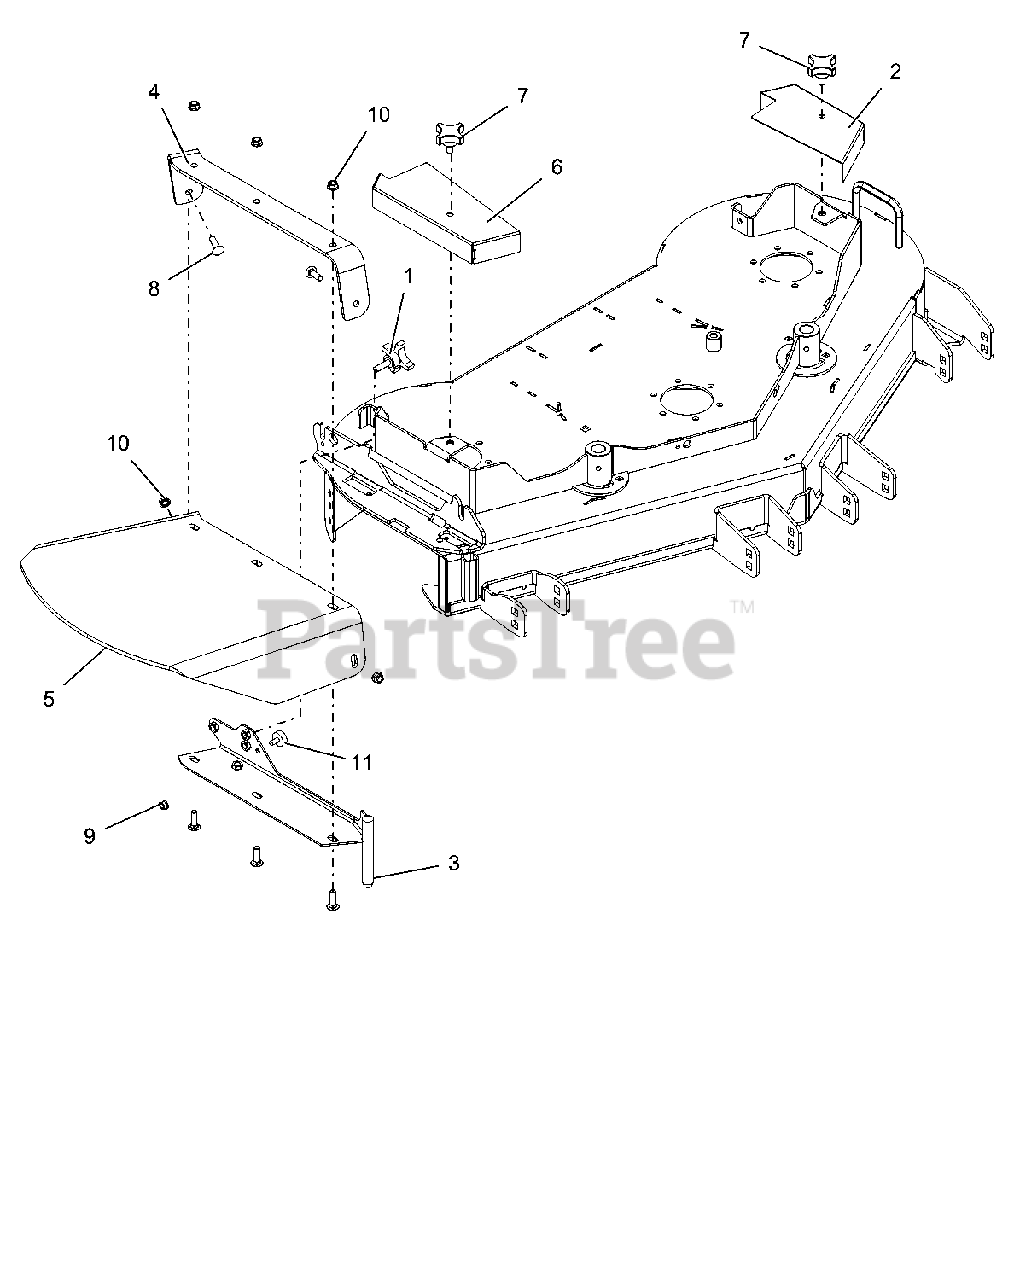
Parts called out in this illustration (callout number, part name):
1	KNOB, 3/8 X 1.25 - 4 PRONG
2	SHIELD, LH SPINDLE 48 FLWLK-RED
3	WLDT. DISCHARGE-RED
4	STRAP, WALK RUBBER DISCHARGE-RED
5	SHIELD, WALK RUBBER DISCHARGE
6	SHIELD, RH SPINDLE 48 FLWLK G2-RED
7	KNOB, 3/8-16 x .75
8	BLT-RDHDSQNK .38-16X1.25 G5 YWZC
9	@NUT-SPNLK-FLG .312-18 YWZC
10	@NUT-SPNLK-FLG .375-16 YWZC
11	BUMPER, RUBBER
